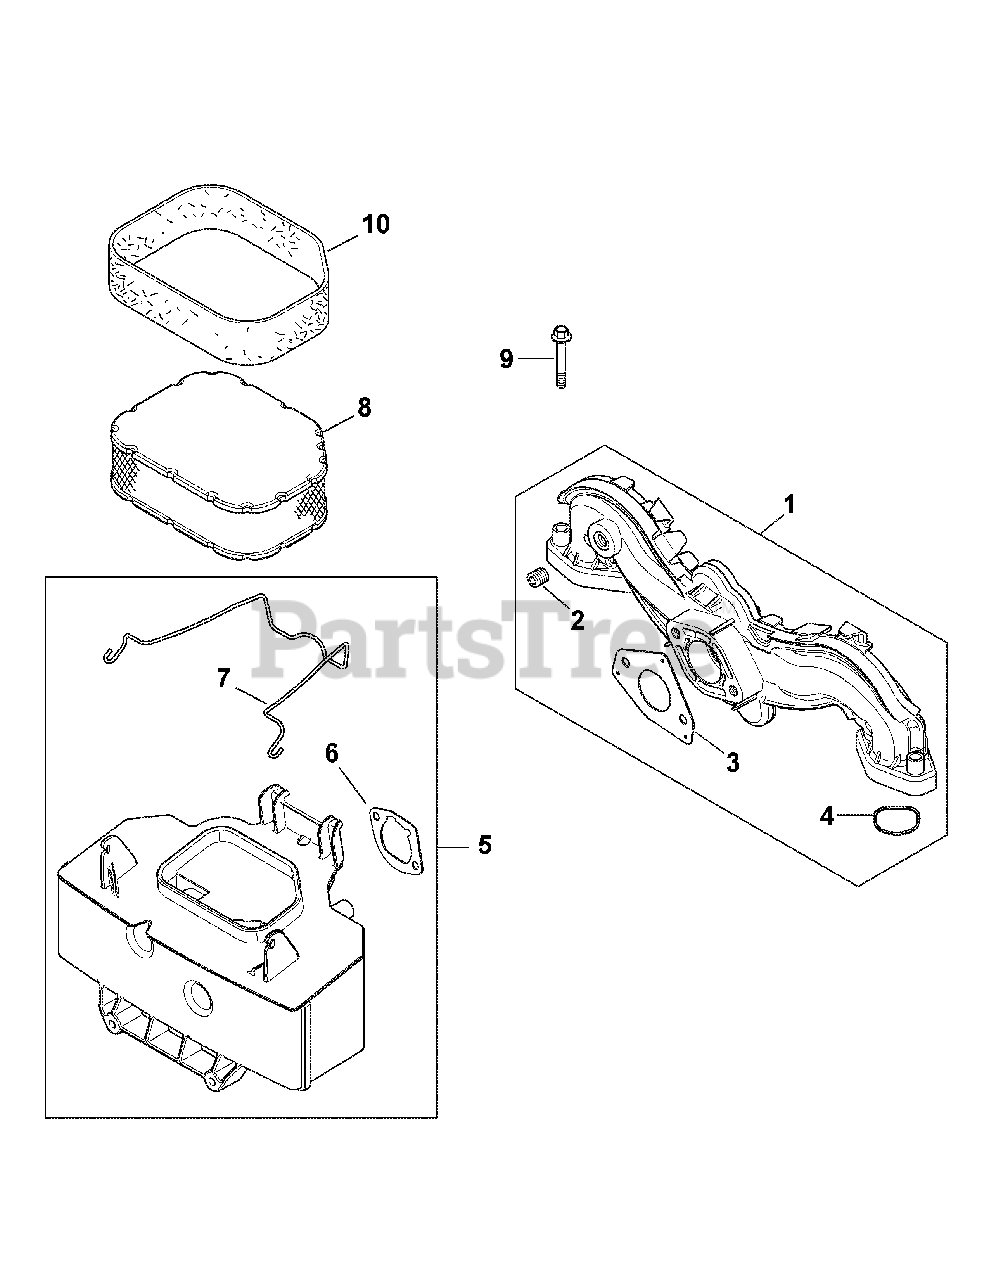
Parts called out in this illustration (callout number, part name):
1	Intake Manifold Kit
2	Carburetor Gasket
3	Intake Port O-Ring
4	Ctsk. Pipe Plug, 1.8
5	Air Cleaner Base Kit
6	Air Cleaner Base Gasket
7	Air Cleaner Element Latch
8	Air Filter & Pre-Cleaner Elements
9	Flg. Screw, M6 x 1.0 x 40
10	Pre-Cleaner Element
